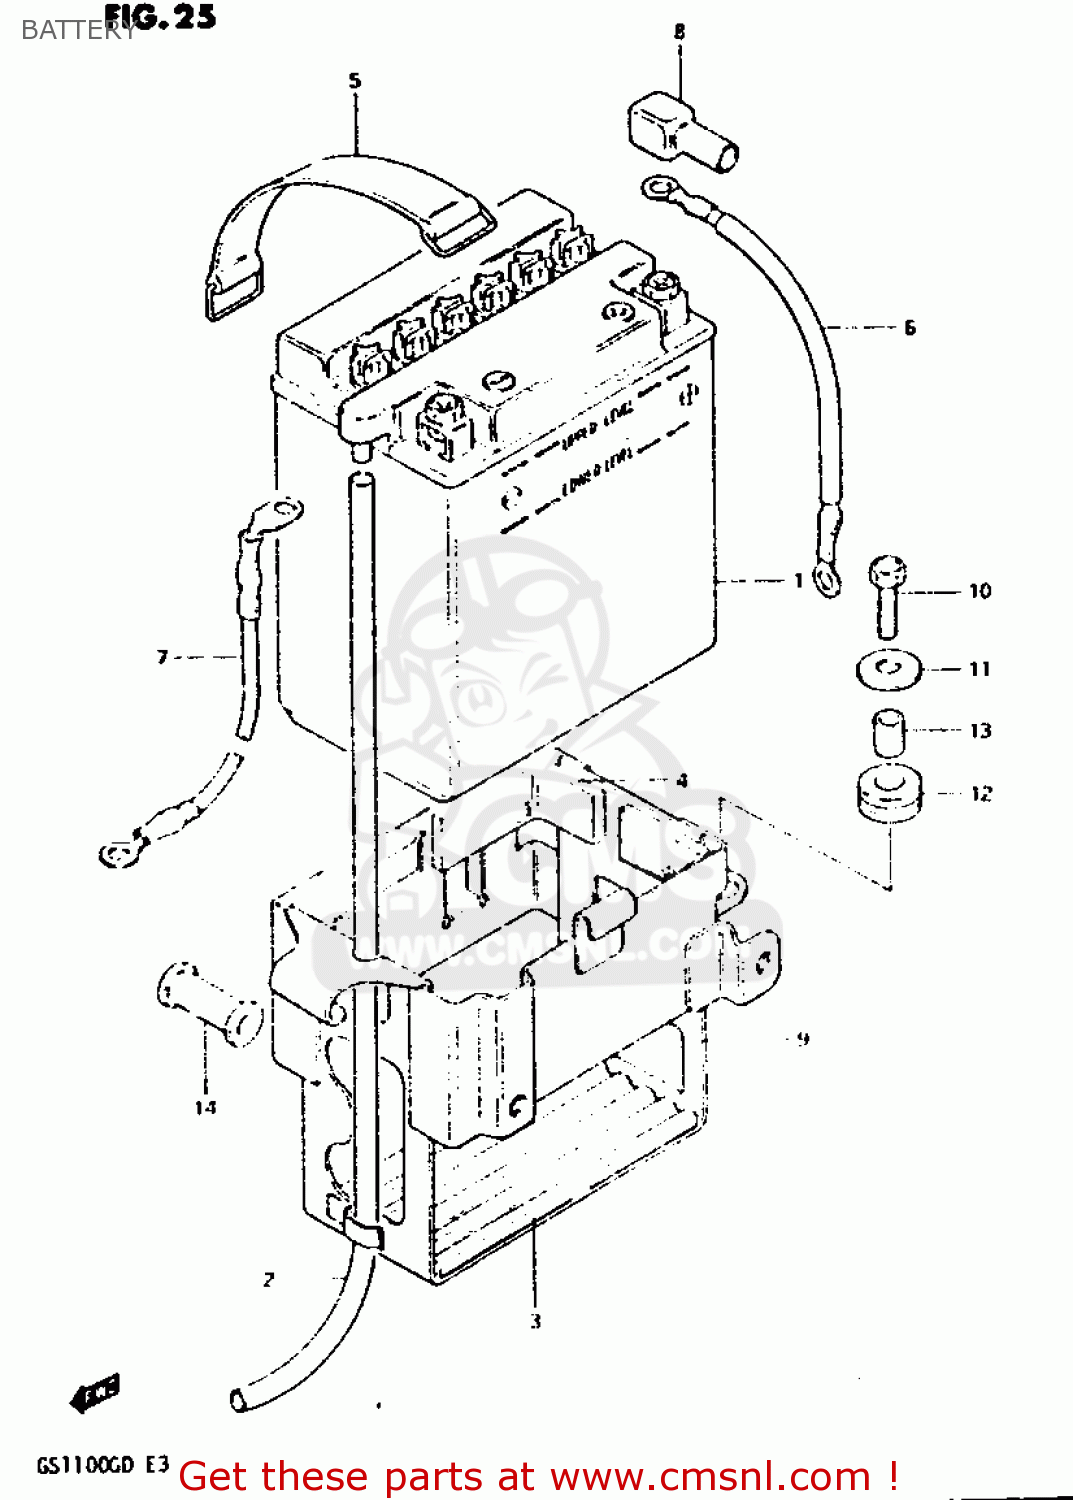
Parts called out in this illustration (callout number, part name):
1	BATTERY ASSY (12V)
2	HOSE,BATTERY EXHAUST
3	PROTECTOR,BATTERY
4	PROTECTOR(170X95X3.0)
5	BAND
6	WIRE,BATTERY PLUS
7	LEAD WIRE,BATTERY(-)
8	CAP,TERMINAL
9	HOLDER,BATTERY
10	BOLT
11	WASHER(6,5X22X1.6)
12	CUSHION
13	SPACER(6.2X8.3X5.7)
14	CUSHION
